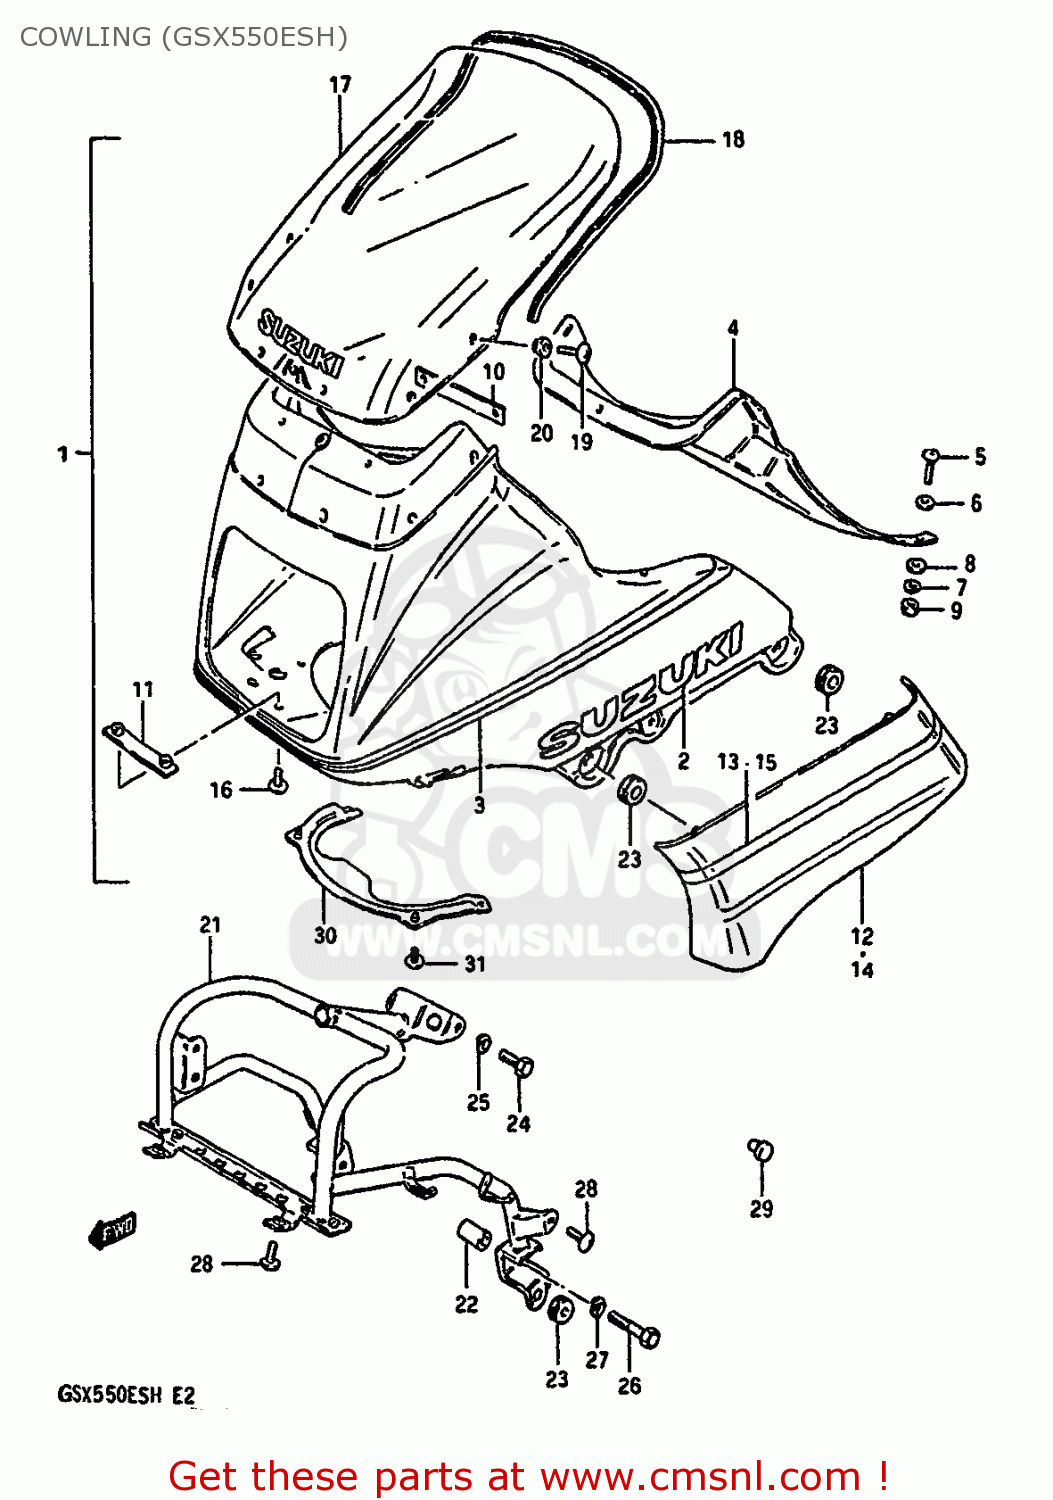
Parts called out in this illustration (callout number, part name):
1	COWLING ASSY (WHITE/RED)
2	EMBLEM,FUEL TA
3	TAPE SET
4	PANEL,COWLING,UPPER
5	SCREW
6	WASHER,5MM
7	WASHER,LOCK
8	WASHER,5MM
9	NUT ,5MM
10	BRACKET,COWLING,UPPER
11	BRACKET,COWLING,LOWER
12	COVER,RH (WHITE/RED)
13	TAPE SET
14	COVER,LH (WHITE/RED)
15	TAPE SET
16	SCREW
17	WINDOW
18	MOULDING
19	SCREW
20	CUSHION
21	BRACE,COWLING
22	SPACER (8.2X12.5X23.5)
23	CUSHION
24	BOLT
25	WASHER,LOCK,8.
26	BOLT
27	WASHER,LOCK,8.
28	SCREW 6X12
29	PLUG
30	COVER,COWLING,LOWER
31	SCREW
